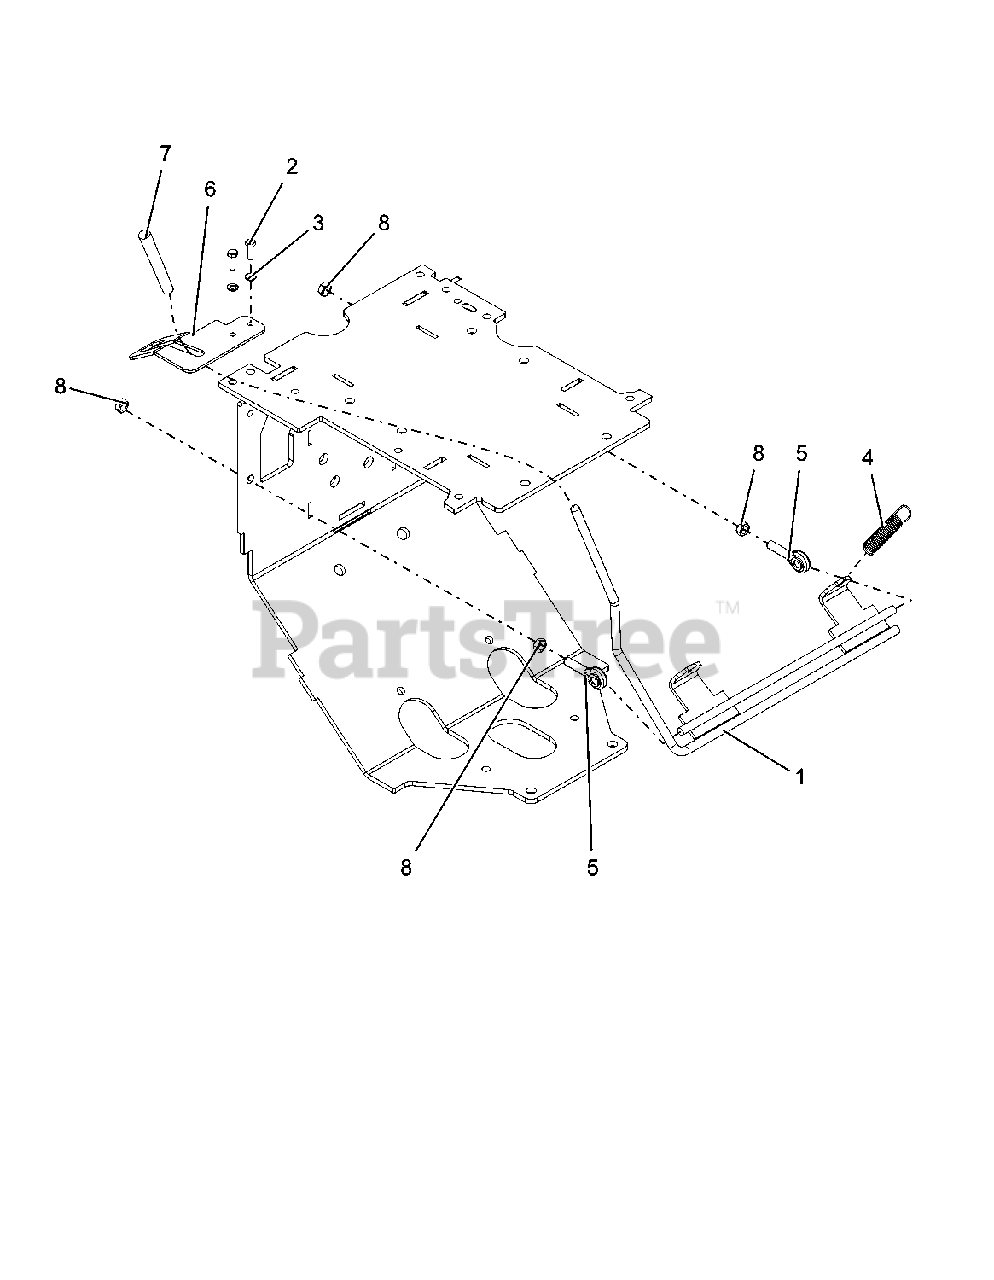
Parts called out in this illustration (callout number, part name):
1	WLDMT, STEERING LOCK-BLACK
2	BLT, HEX M6-1X20 GR8.8 ZC120
3	WSHR-LK .25X.062 REG YWZC
4	SPRG, EXTENSION .063 X .653 X 2.755
5	ROD, END 3/8 RH REV
6	PLATE, STEERING LOCK PROFILE-RED
7	GRIP, PLASTIC
8	NUT, HEX-JAM .375-24 ZC120
